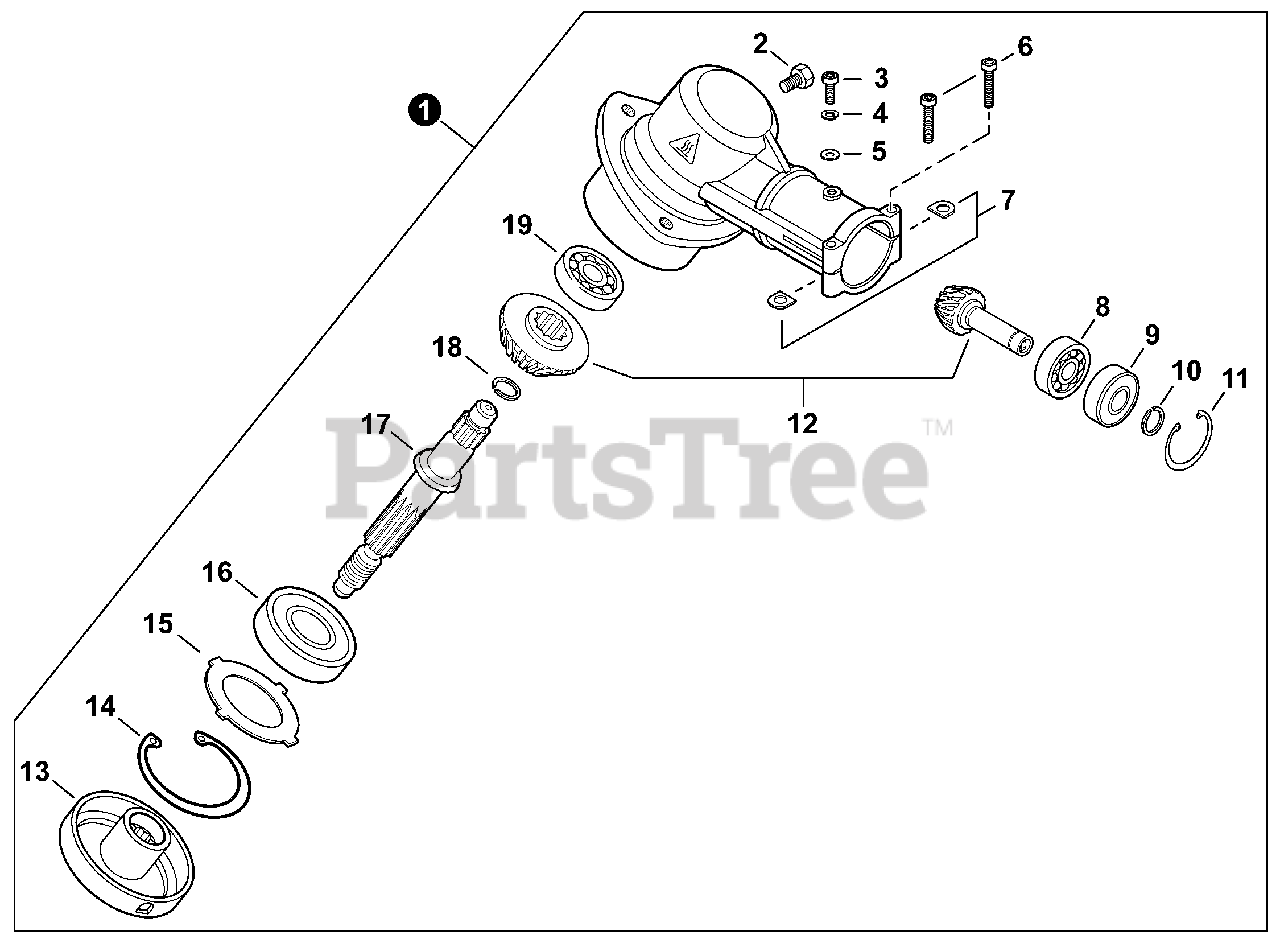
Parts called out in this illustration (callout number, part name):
1	GEAR CASE ASSY
2	BOLT M8×8
3	BOLT, TORX 5×10
4	WASHER, SPRING 5
5	WASHER, FLAT 5.5×10×0.8
6	BOLT, TORX 5×25
8	BEARING, BALL 6900
9	BEARING, BALL 6900Z
10	RING, SNAP Ø10
11	RING, SNAP Ø22
12	GEAR SET
13	PLATE, ADAPTOR - UPPER
14	RING, SNAP Ø32
16	BEARING, BALL 6201
17	SHAFT, GEAR
18	RING, SNAP Ø12
19	BEARING, BALL 609
